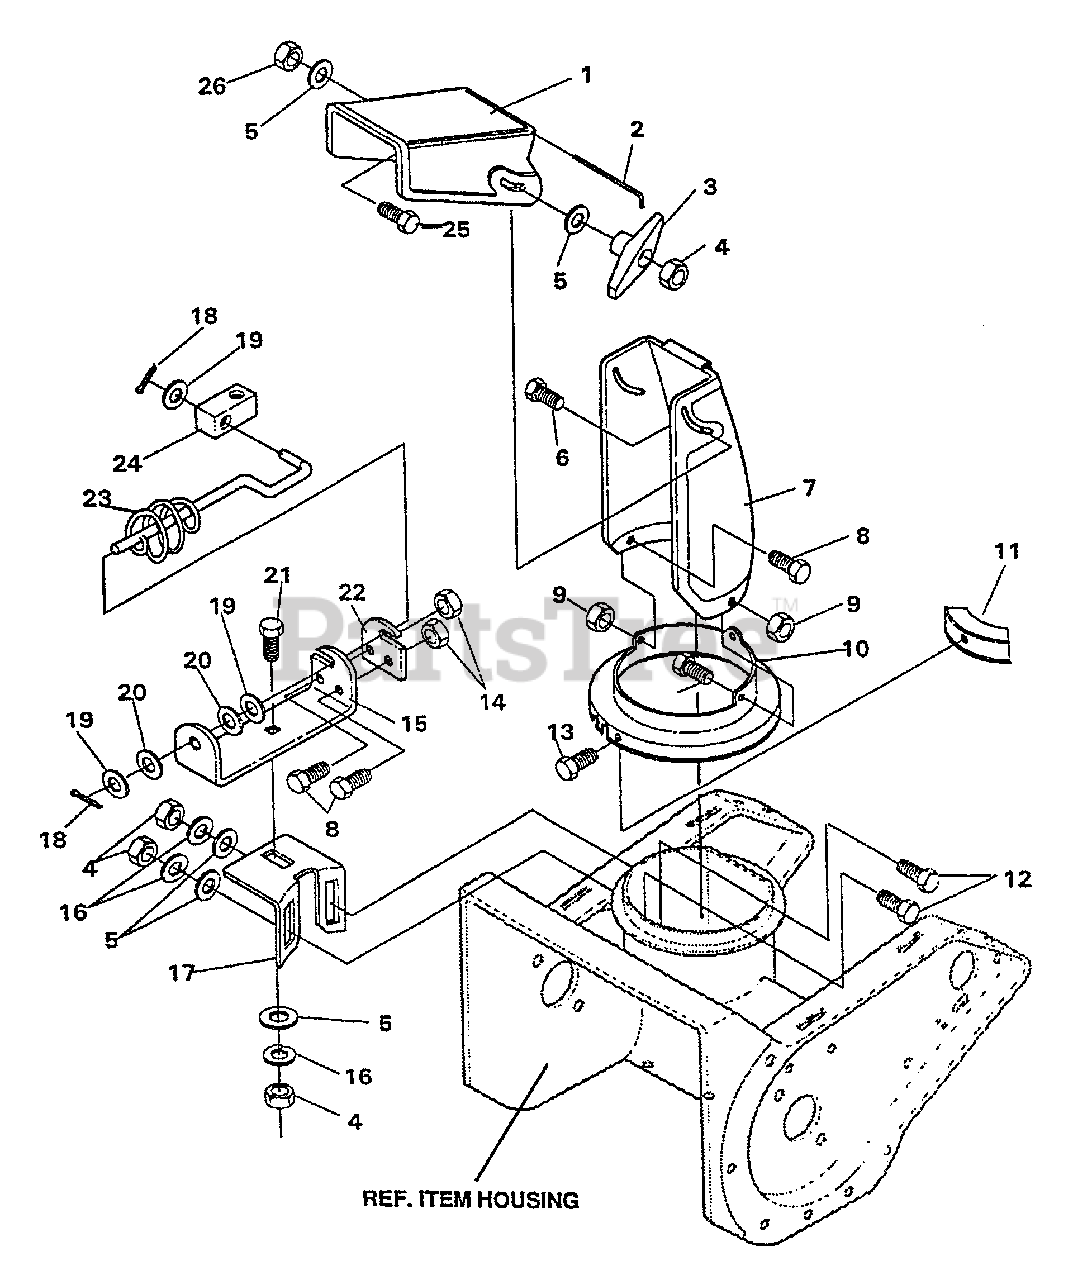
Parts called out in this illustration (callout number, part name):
1	CHUTE ASSY - UPPER
2	WIRE, HINGE 6.65 LONG SR
3	KNOB, T 2 BLADE W/5/16-18 NUT
4	NUT - 5/16-18
5	WASHER
6	BOLT - 5/16-18 X 1.25"
7	CHUTE - LOWER
8	SCREW - 1/4-20 X .50"
9	LOCKNUT - 1/4-20
10	RING, LWR CHUTE
10	RING, LOWER CHUTE
11	CLIP, CHUTE RING PLASTIC
12	BOLT - 5/16-18 X 3/4"
13	SCREW - 1/4-14 X 5/8"
14	NUT - 1/4-20
15	BRACKET, CHUTE ROD
16	LOCKWASHER
17	BRACKET, WORM ADJUST
18	PIN, SPLIT
19	WASHER - .40 X .75 X .025"
20	WASHER - WAVE
21	BOLT - 5/16-18 X 3/4"
22	PLATE, CHUTE ROD
23	CHUTE CONTROL ROD ASSY - LOWER
24	BLOCK, PIVOT PLASTIC
25	SCREW - 5/16-18 X 3/4"
26	NUT - 5/16-18
